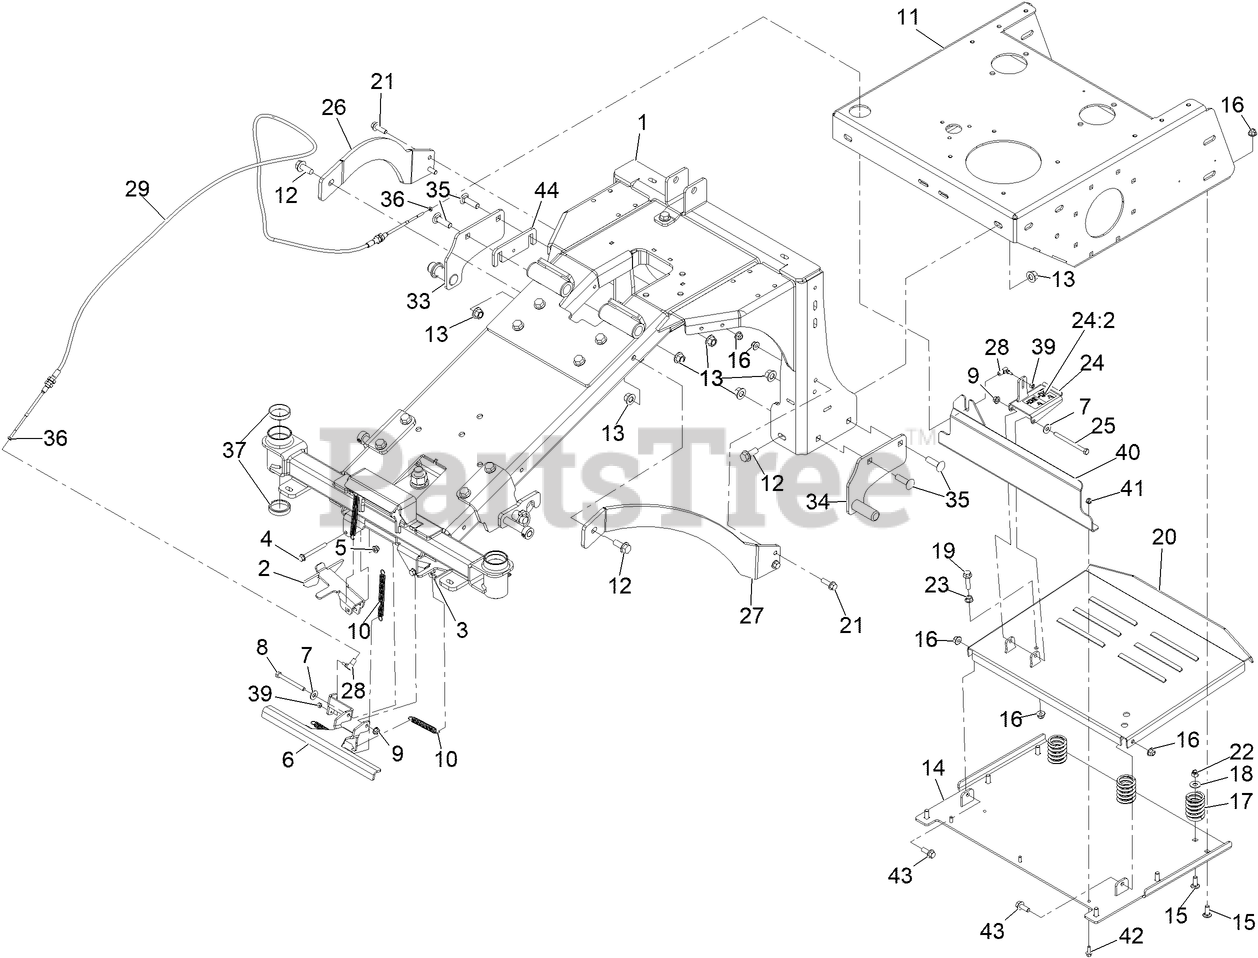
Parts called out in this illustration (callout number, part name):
1	Front Frame ASM
2	WING-CASTER RH
3	WING-CASTER LH
4	SCREW-HHF
5	Nut-Hex Flange
6	ARM-BODY, LCS
7	Washer-Flat
8	SCREW-HH
9	NUT-HF, NI
10	SPRING-EXTENSION
11	REAR FRAME ASM
12	SCREW-HHF
13	Nut-Lock 1/2-13
14	FRAME BASE
15	SCREW-CARR
16	NUT-HF, NI
17	SPRING-COMPRESSION
18	Washer-Flat
19	SCREW-HHF
20	WLD, FOOTPLATE, AE
21	SCREW-HHF
22	NUT-LOCK, NI
23	NUT-HEX FLANGE
24	PEDAL-FOOT
24:2	Decal-Lock, Caster
25	SCREW-HH
26	BRACE-FRAME, RH
27	BRACE-FRAME, LH
28	BALL JOINT-SS
29	ZPLUG LOCKING CASTER CABL
33	PIVOT-BRAKE, RH
34	PIVOT-BRAKE, LH
35	SCREW-CARR
36	Nut,Hex Jam Mch Scr,10-32,Sst
37	BEARING-CUP, TAPERED
39	Nut,NYL Lock,#10-32,ST/ST 18-8
40	SHIELD-HEAT, MUFFLER
42	SCREW-HHF
43	SCREW-HHF 3/8-16 X 1
44	Plate-Spacer-Zplug
